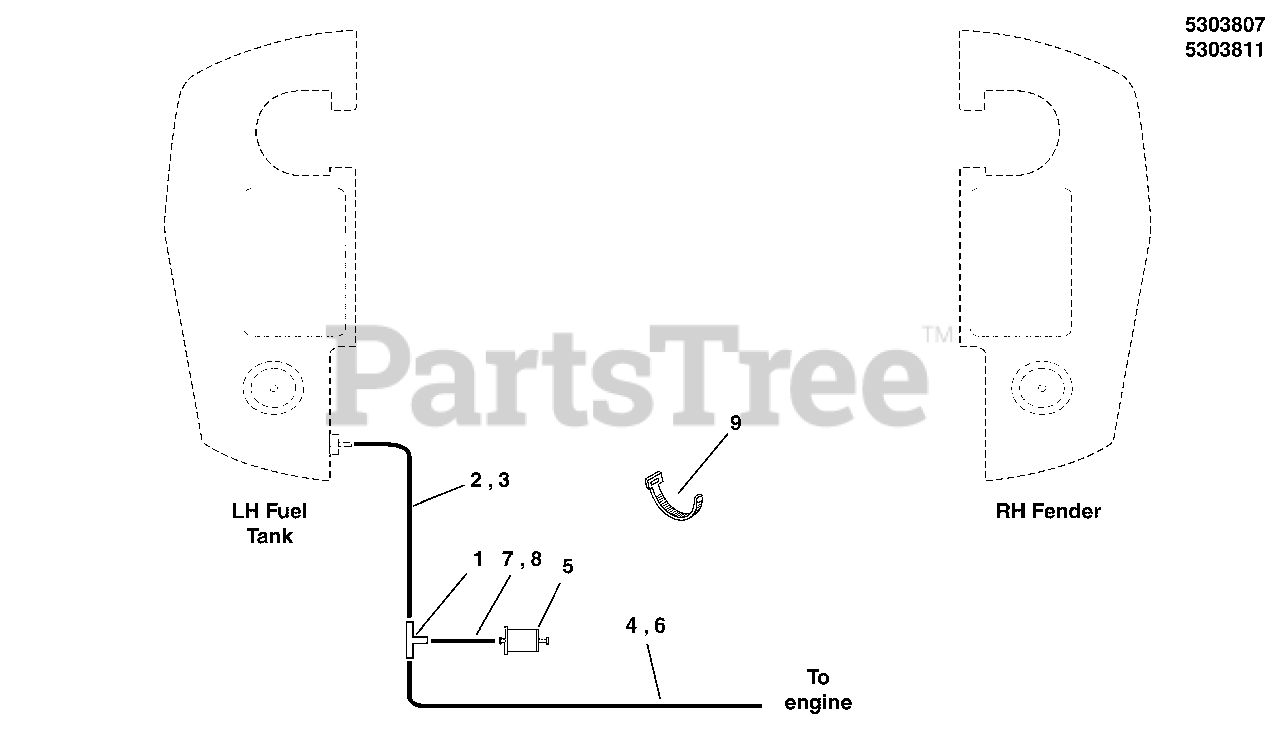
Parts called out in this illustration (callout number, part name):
1	FITTING, 3/16" TEE, BARB TYPE, HDPE
2	HOSE, VAPOR, 5MM ID, 29.00 LG
3	HOSE, VAPOR, 5MM ID, 18.00 LG
4	HOSE, VAPOR, 5MM ID, 12.00 LG
5	FILTER, FUEL
6	HOSE, VAPOR, 5MM ID, 20.50 LG
7	HOSE, VAPOR, 5MM ID, 2.00 LG
8	HOSE, VAPOR, 5MM ID, 16.00 LG
9	TIE,SELF-LOCKING, 6"
